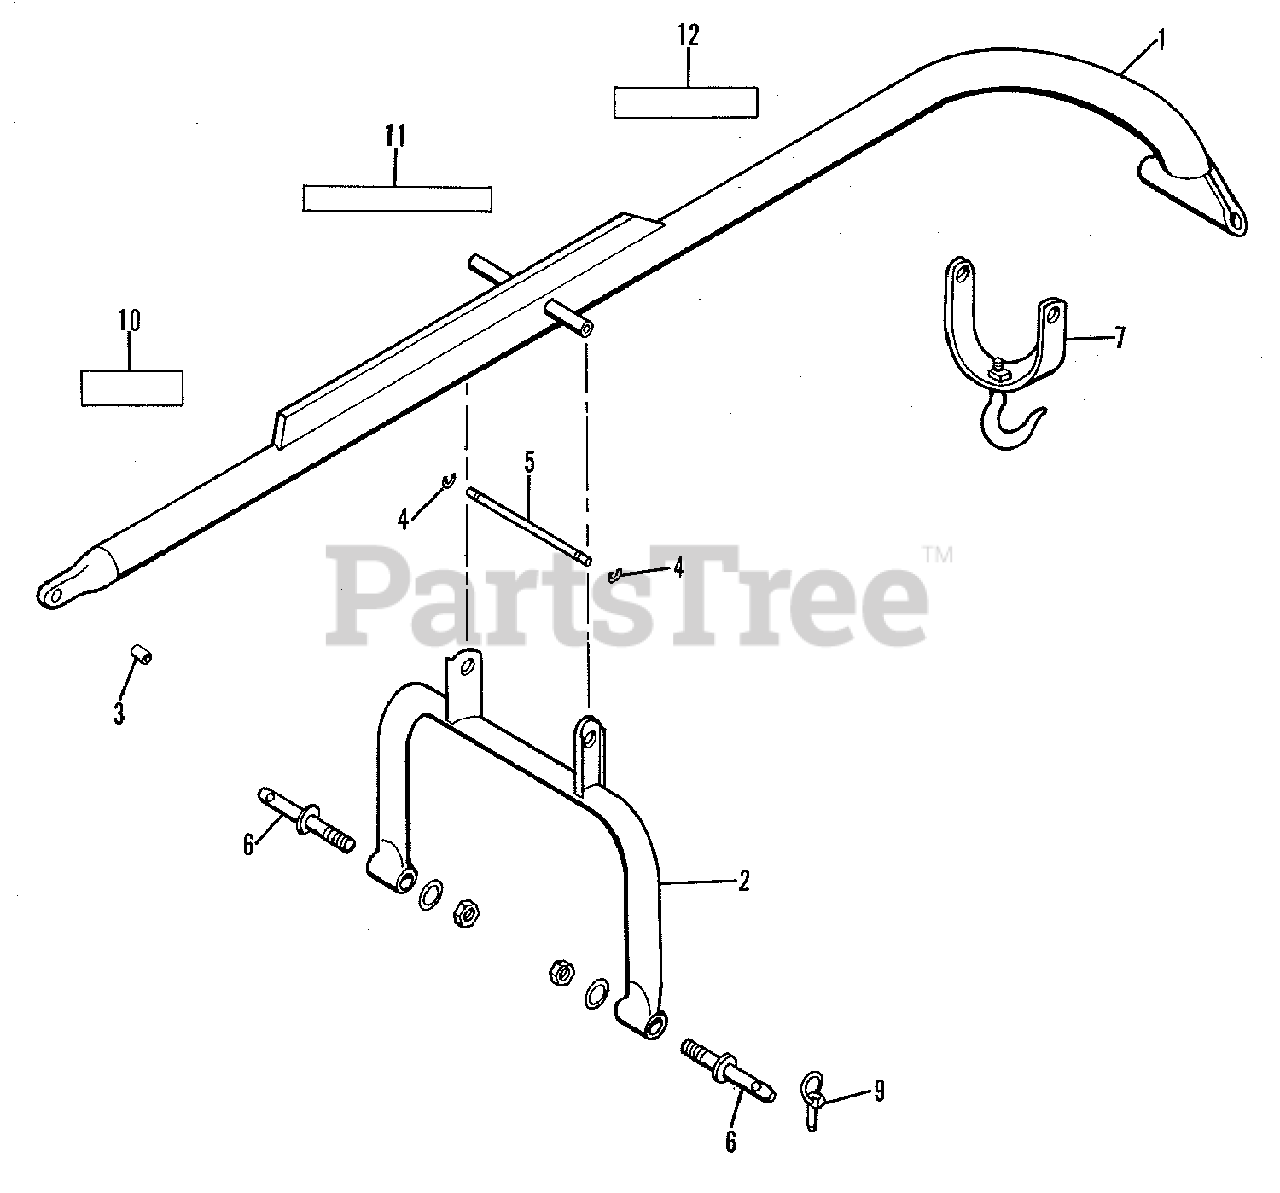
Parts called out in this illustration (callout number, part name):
1	FRAME ASSEMBLY (Cat. l)
1	FRAME ASSEMBLY (Cat. ll)
2	BAIL ASSEMBLY
3	BUSHING, Lower Link
4	RING, Retaining
5	PIN, Bail Retaining
6	PIN, Link Hitch (Cat. l)
6	PIN, Link Hitch (Cat. Ll)
7	HOOK ASSEMBLY, Swivel
8	PIN, Hitch, Frame
10	DECAL, Warning (Safety)
11	DECAL (Allis-Chalmers)
12	DECAL (60 Model Identification)
